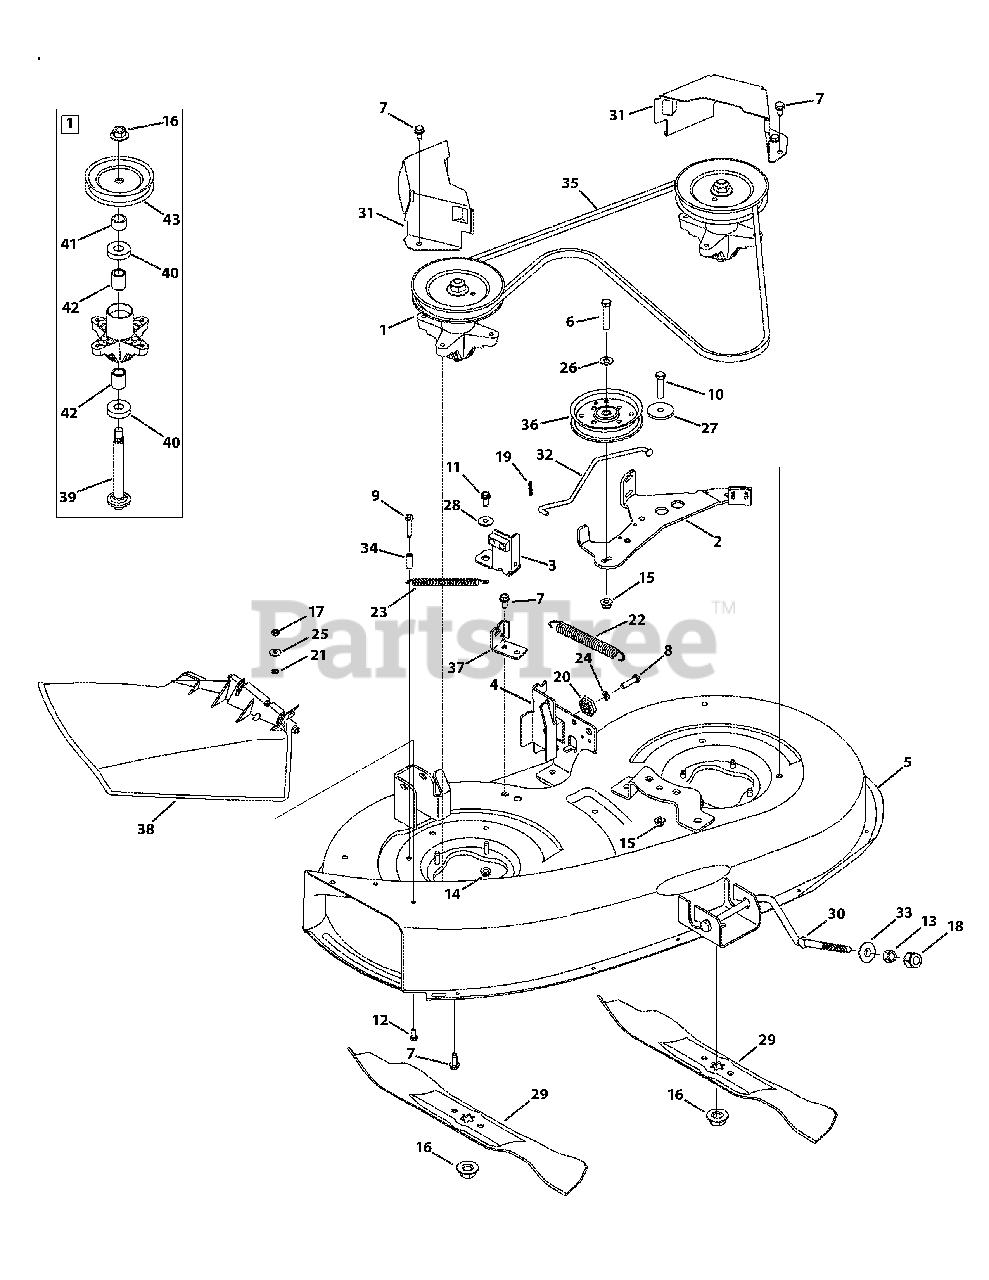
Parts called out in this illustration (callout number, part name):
1	5.75" Pulley Spindle Assembly
2	Deck Brake Assembly
3	Deck Brake Assembly
4	LH Deck Hanger Bracket
5	38" Deck Assembly
6	Hex Screw, 3/8-16 x 1.75
7	Screw, 5/16-18 x .750
8	Hex Screw, 5/16-18 x 1.25
9	Screw, 1/4-20 x 1.50
10	Hex Screw, 3/8-16 x 1.25
11	Hex Screw, 5/16-18 x .75
12	Hex Screw, 1/4-20 x .75
13	Hex Nut, 1/2-13
14	Flangelock Nut, 5/16-18
15	Flangelock Nut, 3/8-16
16	Flange Nut, 5/8-18
17	Hex Nut, 1/4-20
18	Hexlock Nut, 1/2-13
19	Cotter Pin, .072 Diameter
20	Deck Adjuster Gear
21	Push Nut, .25 x .50
22	Extension Spring, .75 x 6.375
23	Extension Spring, .500 x 6.375
24	Lock Washer, 5/16
25	Bell Washer, .265 x .75 x .062
26	Flat Washer, .406 x .875 x .059
27	Shoulder Spacer, .8840 x .190
28	Shoulder Spacer, .5000 x .1475
29	3 in 1 Blade
30	38" Front Adjust Deck Rod
31	Belt Cover
32	38" Brake Control Rod
33	Deck Lift, Pivot Cup
34	Spacer, .260 x .375 x 1.030
35	V Type Belt
36	Idler Pulley
37	Deck Engage Cable Bracket
38	Chute Assembly
39	Spindle Shaft, 5.50
40	Ball Bearing, .787ID x 1.85 OD x .551
41	Spacer, .820 x 1.150 x .480 LG
42	Spacer, .80 x 1.10 x 1.322 LG
43	Deck Pulley, 5.75
